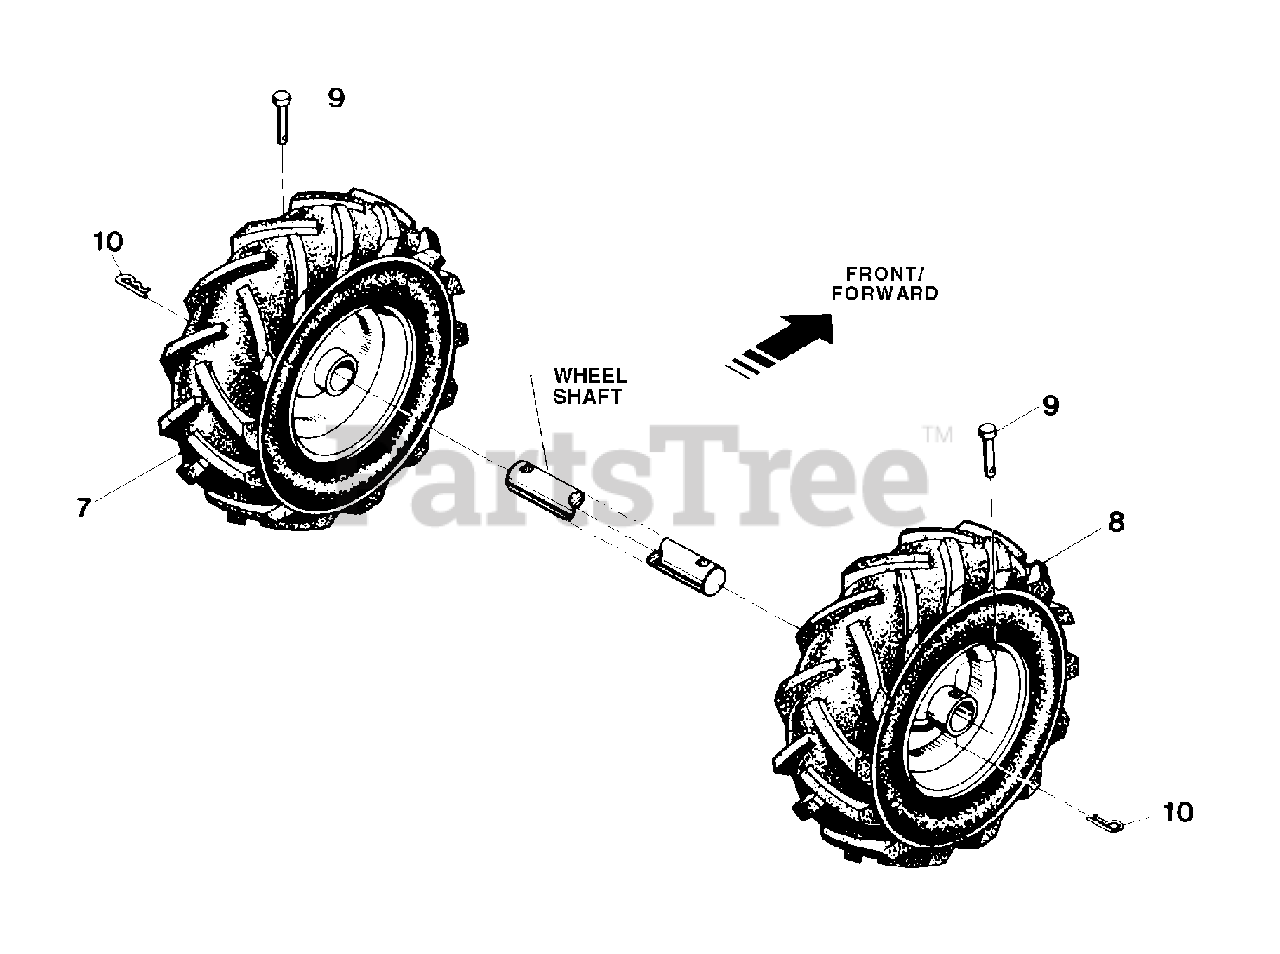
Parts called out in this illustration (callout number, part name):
7	Wheel & Tire Assy-Left Side
8	Wheel & Tire Assy-Right Side
9	Clevis Pin-.312 x 1-3/4, secures wheel hub to wheel shaft
10	Hair Pin Cotter
